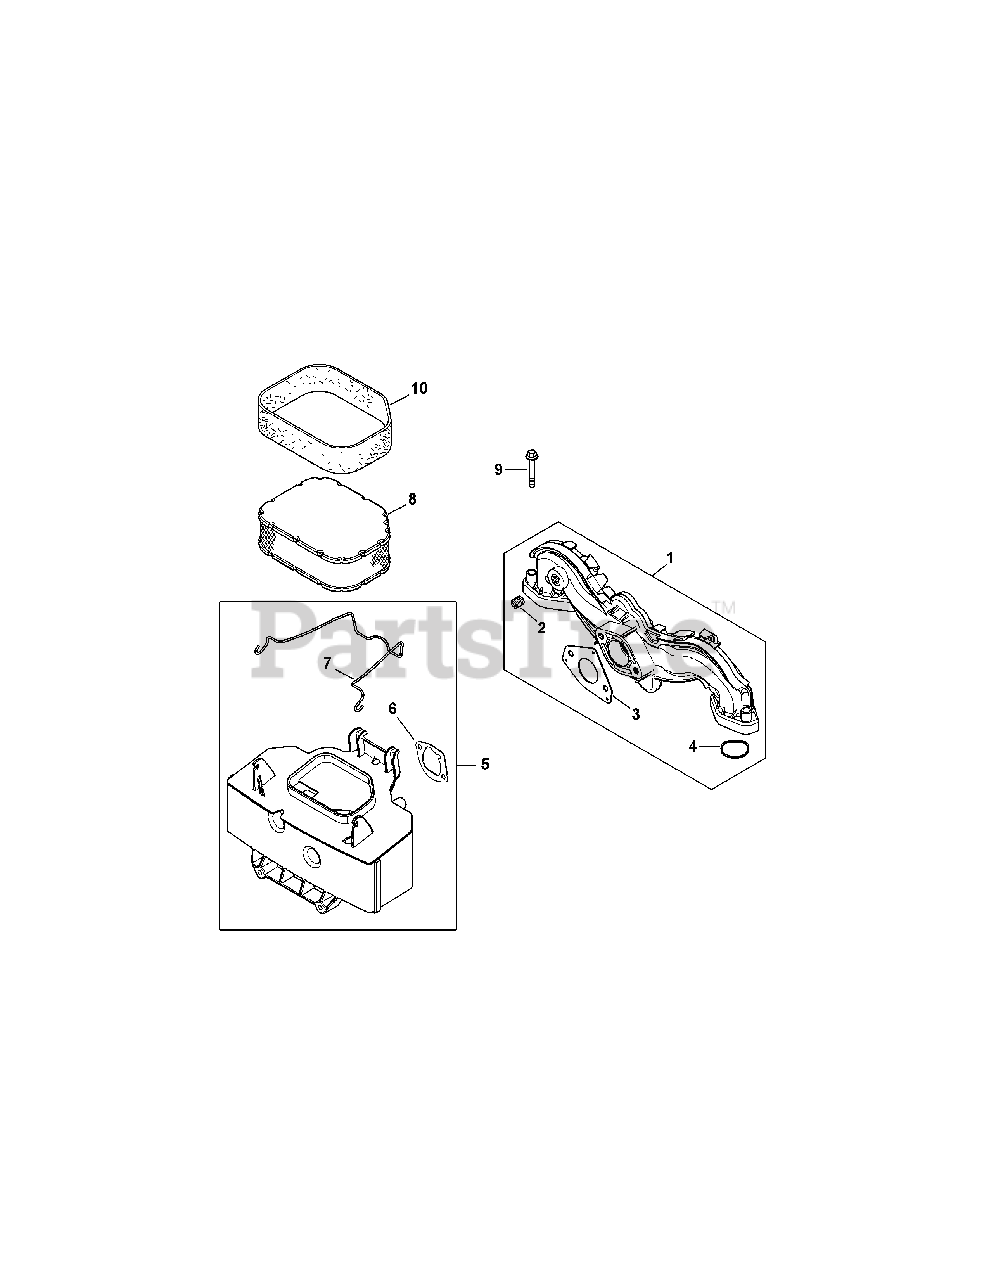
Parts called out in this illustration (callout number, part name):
1	Intake Manifold Kit (Inc. 2-4)
2	Pipe Plug, 1/8"
3	Carburetor Gasket
4	Intake Port O-Ring
5	Air Cleaner Base Kit (Inc. 5 & 6)
6	Air Cleaner Base Gasket
7	Air Cleaner Element Latch
8	Air Filter Element
9	Flg. Screw, M6 X 1.0 X 40
10	Pre-Cleaner Element
